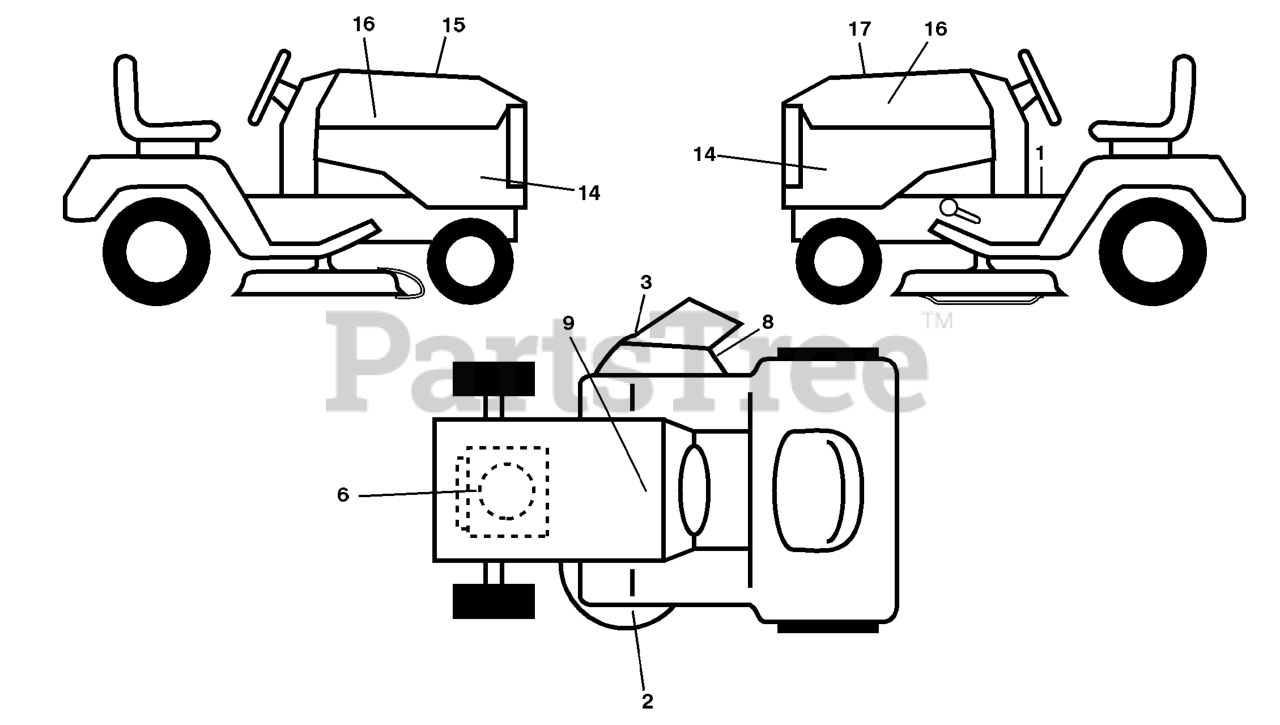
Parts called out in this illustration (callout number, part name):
1	DECAL.FENDER.WARNING.ENG
2	DECAL.DECK.AIR.INDUCTION.HUSQ
3	DECAL.WARN.KEEP.HAND.AWAY
6	DECAL.ENG.BSM44.ED.27HP.278171
8	DECAL.MOWER.SCH.48/54
9	DECAL BTRY SYMBOLS
14	DECAL.SDPNL.2748GLS.ENDUR.HUSQ
15	DECAL HOOD CUST. RESP.
16	EMBLEM.HOOD.HUSQ.DEALER
17	Decal, Replacement
17	DECAL.BYPASS.FENDER.CRD.LT.YT
17	PAD.FOOTREST.LH.HUSQ.T
17	PAD.FTRST.RH.PCH.HUSQ.
17	Manual, Owner's
